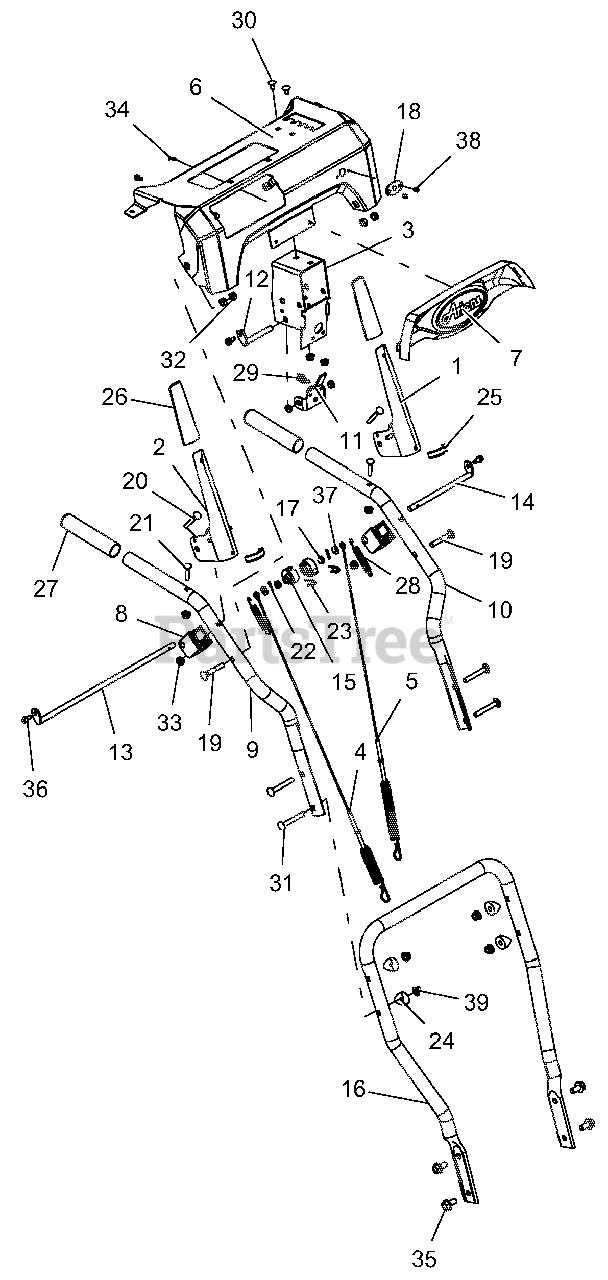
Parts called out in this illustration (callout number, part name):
1	LEVER, CLUTCH-LH
2	LEVER, CLUTCH-RH
3	WELDMENT, BRACKET INTERLOCK
4	CABLE, AUGER (DELUXE & PRO)
5	CABLE, UPPER TRACTION
6	KIT, CONTROL PANEL W/DECAL
7	DASH BEZEL, ARIENS LOGO - COMP
8	BLOCK, CLUTCH PADDLE
9	HANDLEBAR, UPPER - RH
10	HANDLEBAR, UPPER - LH
11	BRACKET, INTERLOCK ARM
12	ROD, PIVOT - INTERLOCK
13	ROD, PADDLE MOUNT - LONG
14	ROD, PADDLE MOUNT - SHORT
15	CAM, INTERLOCK
16	HANDLEBAR, LOWER - SM DELUXE
17	BUSHING, POLYLINER-.38 SNAPIN
18	BSHG, CHUTE CRANK
19	BLT-RDHDXLSQNK .31-18X2.0 G5YZ
20	BLT-RDHDXLSQNK .25-20X2.0 G5YZ
21	BLT-RDHDXLSQNK.25-20X1.25 G5ZC
22	PIN-HAIR INT .06X.18X.77
23	PIN, SPRING CLIP
24	SPACER, HANDLEBAR
25	EDGING, CLUTCH PADDLE - 2.00"
26	CLUTCH PADDLE SLEEVE - GRAY
27	HANDLE GRIP
28	SPRING, EXTENSION
29	SPRING-EXT .047X.438X1.45
30	@BLT-RDHDSQNK .25-20X.50 G5YZ
31	@BLT-RDHDSQNK .31-18X2.25 G5YZ
32	@NUT-LK-CTR .31-18 YWZC
33	@NUT-LK-TOP-FLG .25-20 YWZC
34	SCR-TAP #10X.50 BOSS INDHXHD
35	BLT-SERHFWH .38-16X.75 YWZC
36	SCR-TAP .25-20X.50 HWH TR YWZ
37	@WSHR-FL-STL.281X.62X.065 YWZC
38	RVT-POP #43 .125X.313 STL ZINC
39	@NUT-LK-NYL-FLG .31-18 YWZC
